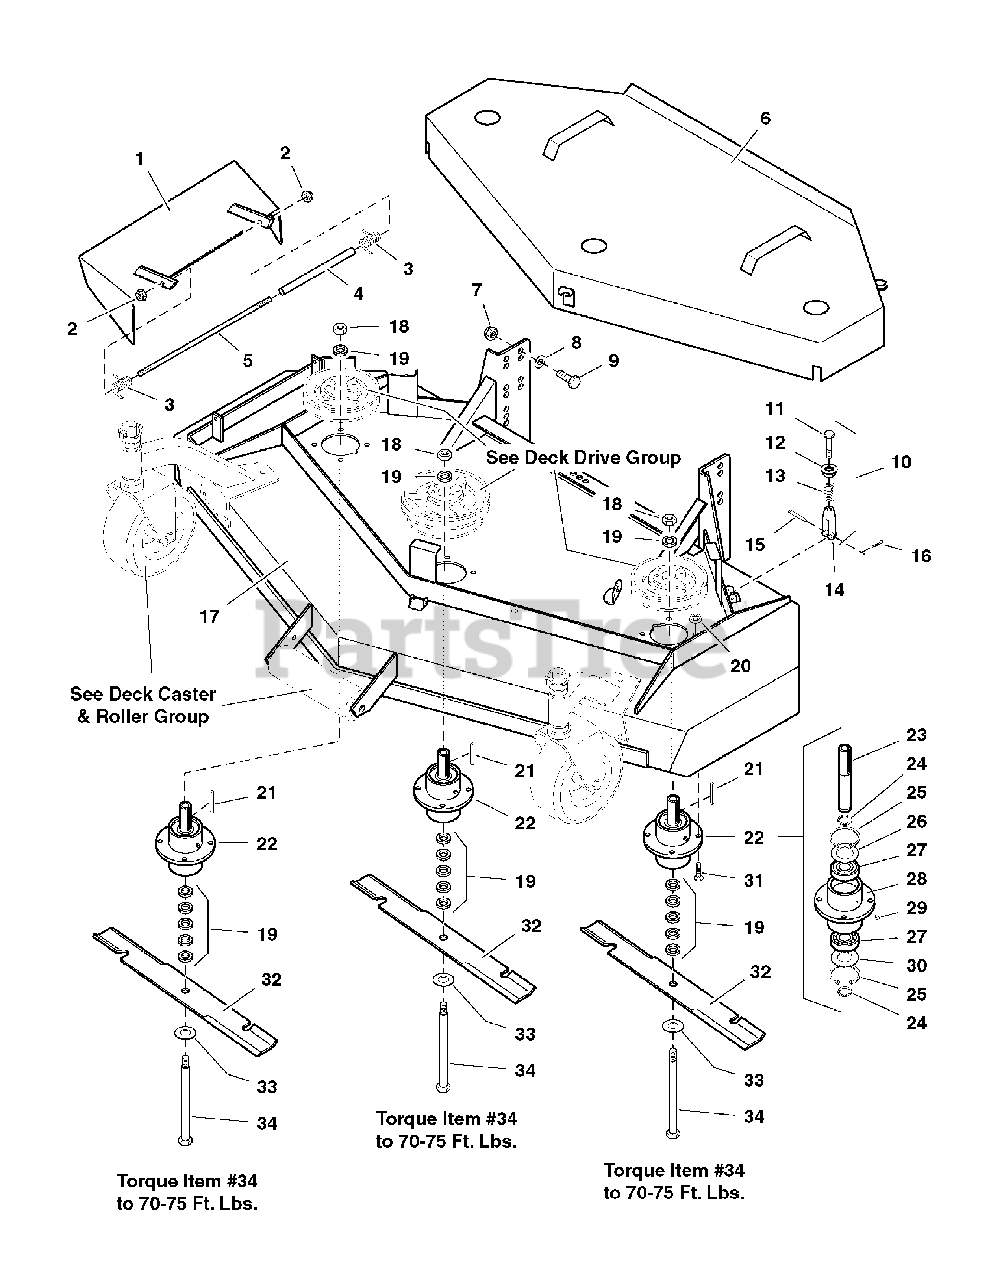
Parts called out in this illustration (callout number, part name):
1	CHUTE, Discharge
2	NUT, Hex, Nylon Lock, 5/16-24
3	SPRING, Torsion
4	SPACER, Spring
6	SPINDLE COVER
7	NUT, Hex, Nylon Lock, 1/2-20
8	WASHER, 1/2
9	CAPSCREW, Hex Hd, 1/2-20 x 1-1/4
10	GUARD HOLD DOWN, Complete (includes Ref 11-14)
11	CAPSCREW, Hex Hd, 5/16-18 x 2
12	NUT, Hex, Serrated Flange, 3/8-16
13	SPRING, Guard Hold Down
14	CLEVIS, 5/16-24
15	PIN, Clevis
16	PIN, Cotter
17	61" MOWER HOUSING
18	NUT, Hex, 5/8-11
19	SPACER, Blade
20	NUT, Hex, Serrated Flange, 5/16-18
21	KEY, 1/4 Sq. x 2-1/2
22	SPINDLE ASSEMBLY, Complete (includes Ref 23-30)
23	SPINDLE SHAFT
24	SNAP RING, External
25	SNAP RING, Internal
26	SPINDLE WASHER, Top
28	SPINDLE HOUSING
29	GREASE FITTING
30	SPINDLE WASHER, Bottom
31	CAPSCREW, Hex Hd, 5/16-18 x 1-1/4
32	MOWER BLADE
33	WASHER, USS, 5/8
34	CAPSCREW, Hex Hd, 5/8-11 x 9-1/2
